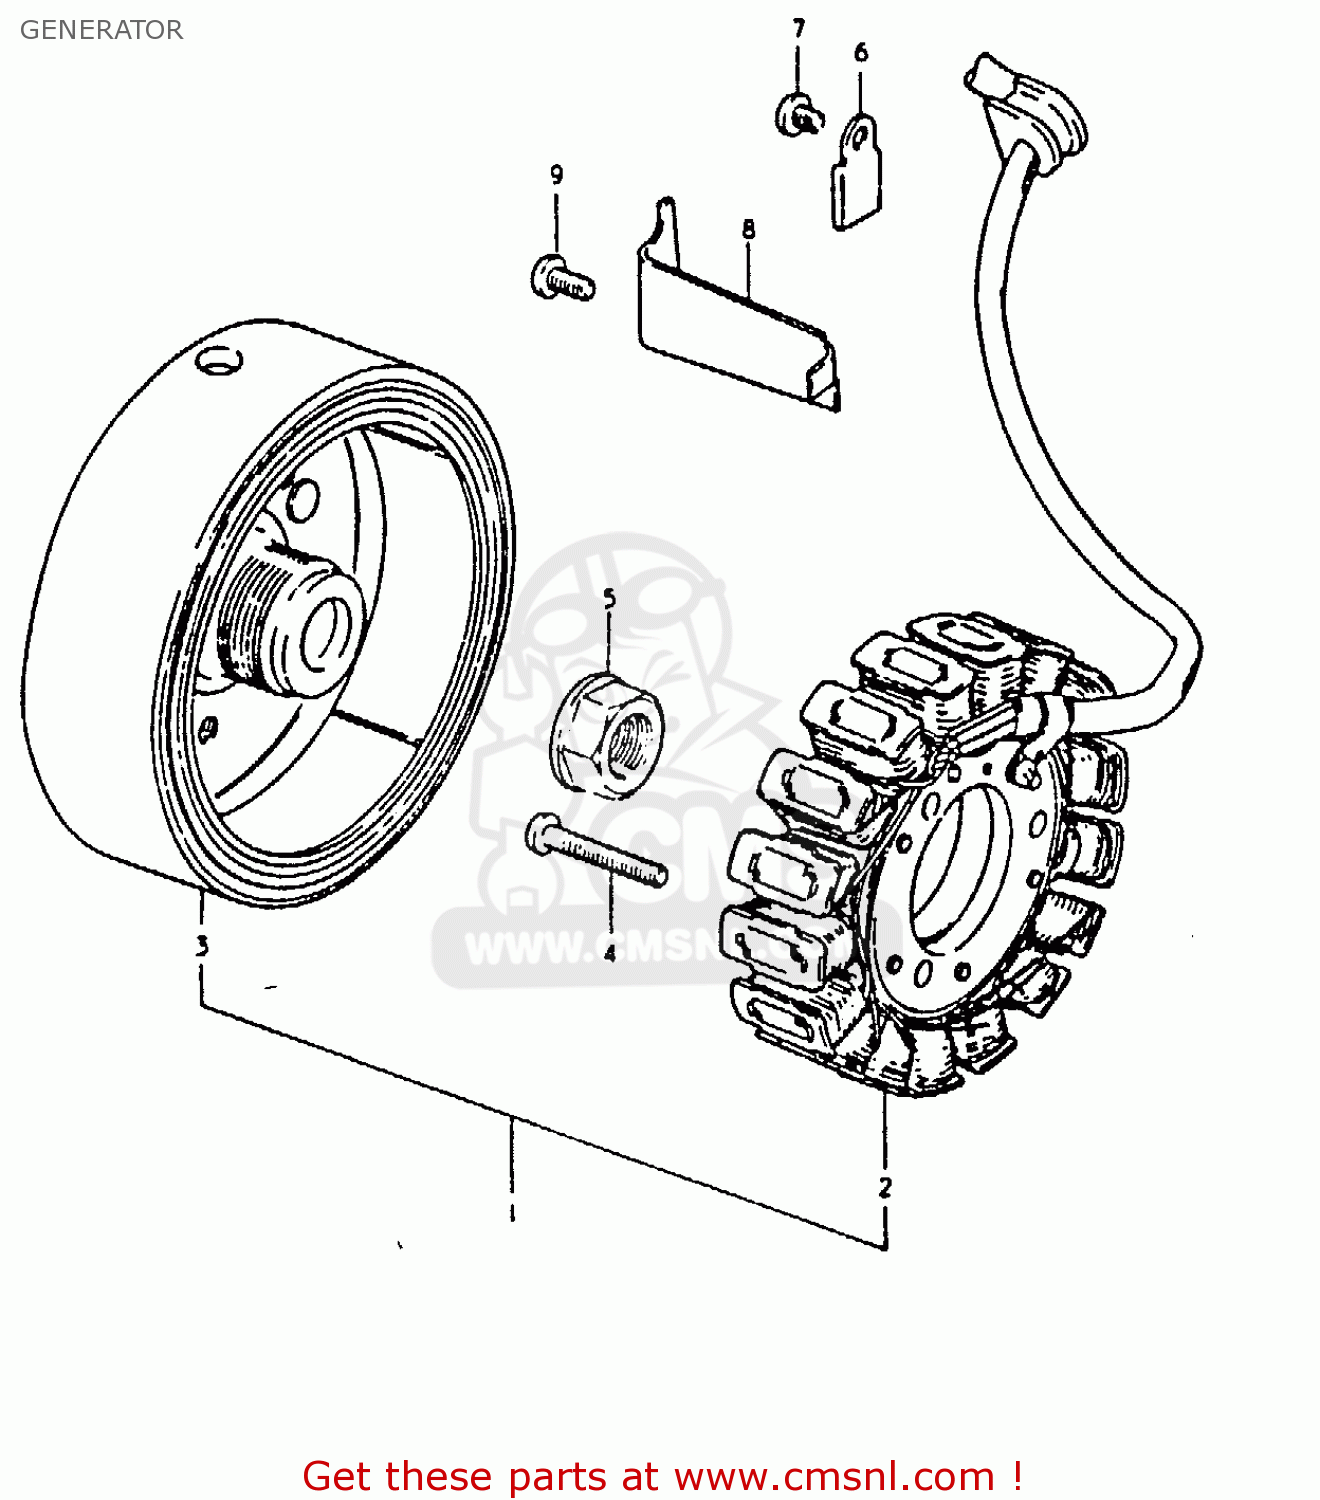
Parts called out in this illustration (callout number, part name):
1	GENERATOR ASSEMBLY
2	STATOR ASSEMBLY
3	ROTOR ASSEMBLY
4	SCREW 6X30
5	NUT,GENERATOR ROTOR
6	CLAMP,GENERATOR LEAD WIRE
7	SCREW
8	CLAMP,GENERATOR LEAD WIRE
9	SCREW
